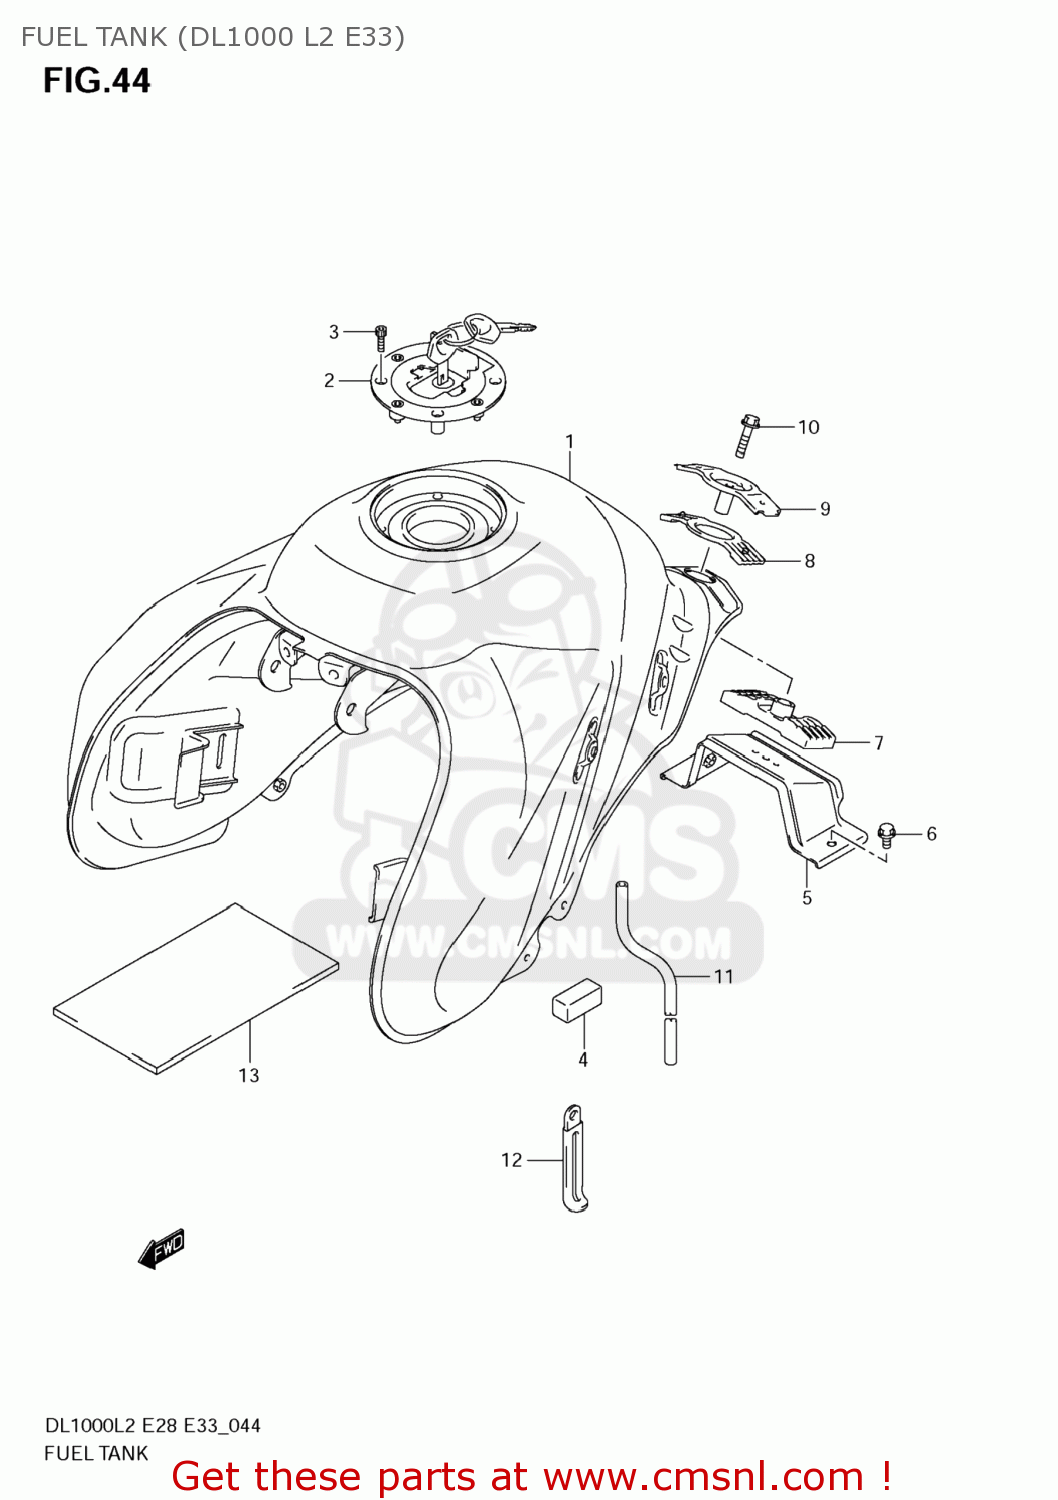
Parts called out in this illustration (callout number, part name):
1	TANK ASSY,FUEL(RED)
2	CAP SET,FUEL TANK
3	BOLT(5X20)
4	CUSHION,FUEL TANK SIDE
5	BRACKET,FUEL T
6	BOLT
7	CUSHION,FUEL TANK RR LWR
8	CUSHION,FUEL TANK RR UPR
9	BRACKET,FUEL TANK RR UP
10	BOLT
11	HOSE,FUEL TANK WATER DRAIN
12	CLAMP(L:45)
13	SHIELD,FUEL TANK CTR
